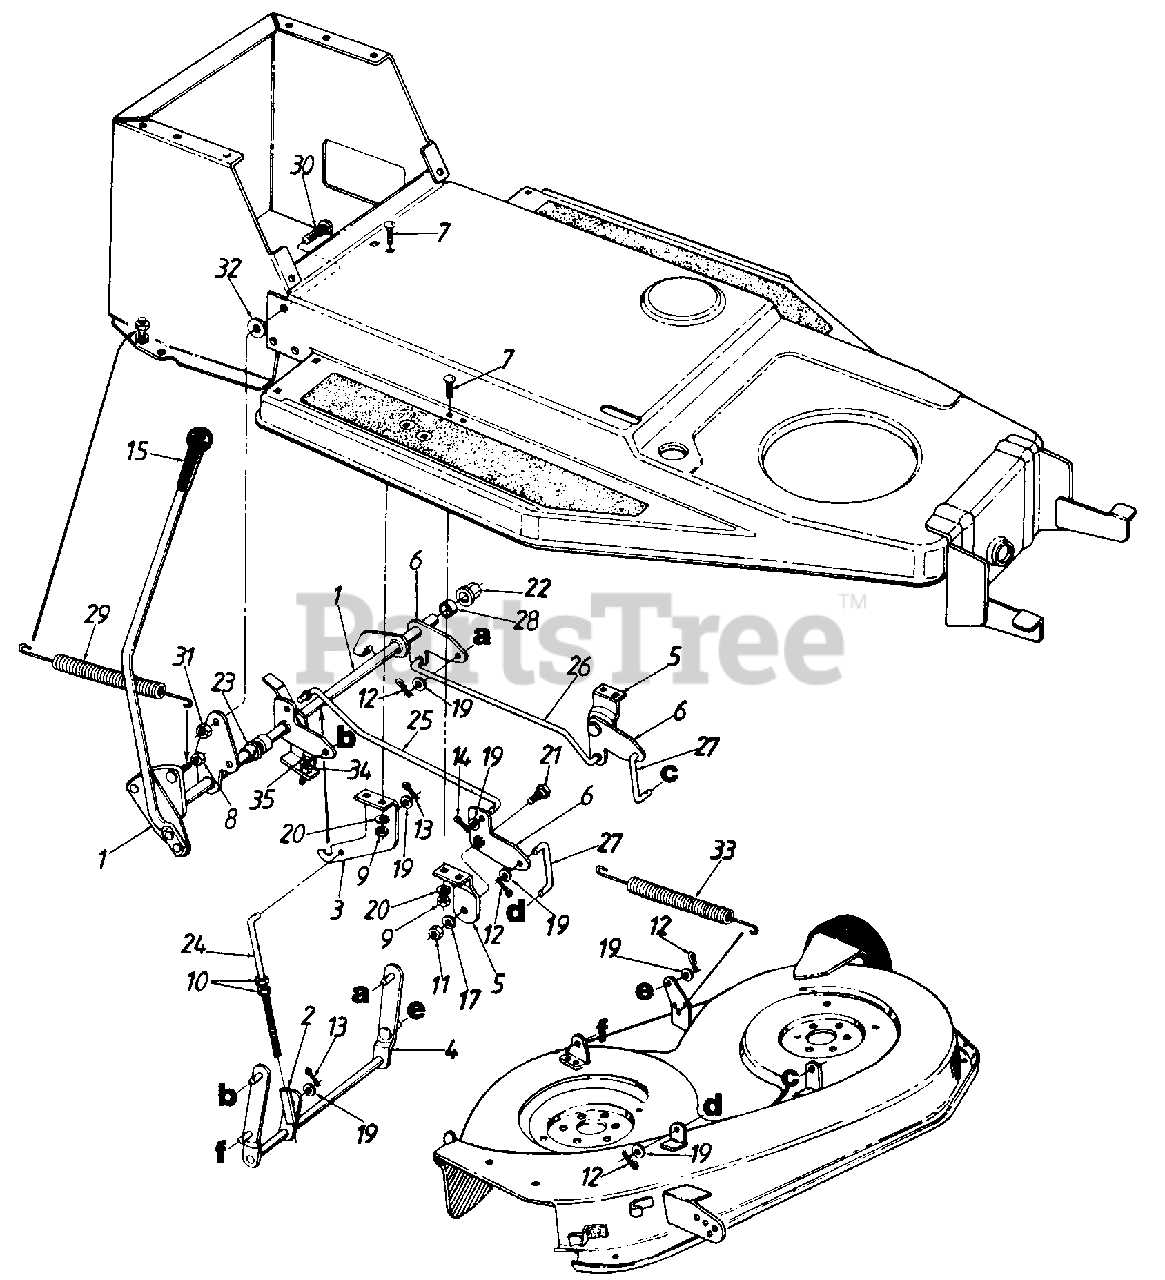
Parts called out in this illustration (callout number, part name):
1	Lift Shaft Ass'y.
2	Pivot Sleeve Ass'y.
3	Deck Lock Out Brkt.
4	Stabilizer Ass'y.
5	Deck Lift Hanger
6	Deck Lift Float Brkt.
7	Carr. Bolt 1/4-20 x .62" Lg.
8	Hex L-Nut 5/16-18 Thd.
9	Hex Nut 1/4-20 Thd.
10	Hex L-Nut 3/8-24 Thd.
11	Hex Nut 3/8-16 Thd.
12	Intern. Cot-Pin 5/16" Dia.
13	Cot-Pin 1/8" Dia.
14	Cot-Pin 3/32" Dia.
17	L-Wash. 3/8" I.D.
19	Fl-Wash. .406" I.D. x .75" O.D.
20	L-Wash. 1/4" I.D.
21	Shld Bolt .625 Dia. x .425" Lg.
22	Hex Flange Brg.
23	Nyliner Flanged Brg.
24	J-Bolt 3/8-16 x 5.25" Lg.
25	Connecting Rod-R.H.
26	Connecting Rod-L.H.
27	Lift Link
28	Spacer
29	Spring 8.65" Lg.
30	Ribbed Neck Bolt 3/8-24 x .80" Lg.
31	Hex Nut 3/8-24 Thd.
32	Fl-Wash. 3/8" I.D.
33	Deck Spring 10.33" Lg.
34	Hex Nut 5/16-18 Thd.
35	Hex Wash. Hd. Tap Scr. 5/16-18 x 1.0" Lg.
